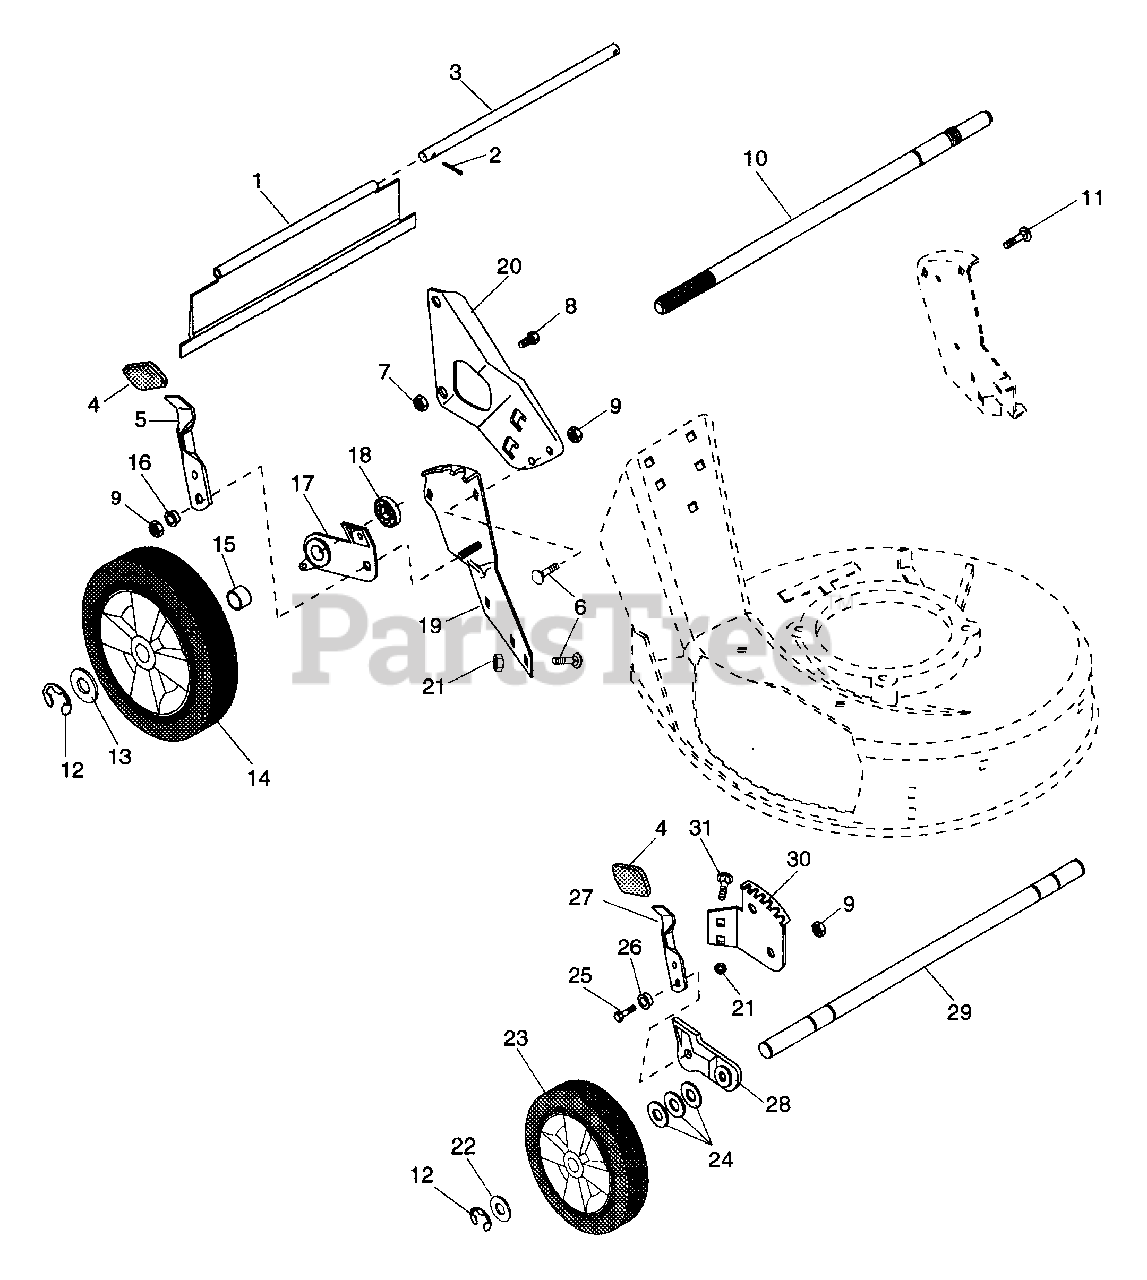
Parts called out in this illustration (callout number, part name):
1	REAR PROTECTIVE GUARD, PUSH
1	REAR PROTECTIVE GUARD, S.P.
2	PIN-COTR .06X.50
3	ROD
5	HEIGHT ADJUSTMENT LEVER
6	BLT-RDHDSQNK .312-18X.62SHTPL
7	NUT-LK-JAM-CTR .375-16 PL
8	HANDLEBAR STUD
9	NUT-LK .312-18 GR A PL
10	REAR AXLE,5/8 DIA
10	REAR AXLE-PUSH MOWER MM
10	REAR AXLE-PUSH MOWER
11	BLT-RDHDSQNK .31-18X1.0 SHT PL
12	RG-RTNG-EXT .500X.042 (E)
14	LH WHEEL
14	RH WHEEL
14	WHEEL
14	RH REAR WHEEL
14	LH REAR WHEEL
14	TIRE 10X1.75
14	10 1/2 TIRE SKIN
15	SPACER TUBE,PUSH LH
15	SPACER TUBE PUSH RH
15	SPACER TUBE, SELF PROPEL
16	BSHG-FLG .32X.500X.344X.880
17	REAR BRACKET & BEARING ASSEMBL
17	REAR BRACKET & BEARING ASSY RH
17	R.H. REAR ADJUSTOR BRACKET
17	REAR ADJUSTMENT BRACKET L.H.
17	L.H. REAR ADJUSTOR BRACKET
17	BRG-BALL .625X1.383X.50
19	QUADRANT, REAR - L.H.
19	REAR QUADRANT, R.H.
20	RH HANDLEBAR MTG. BRKT.
20	LH HANDLEBAR MTG. BRKT.
21	NUT-FLG. .312-18 PL
22	WSHR-FL-STL .505X.880X.072 PL
23	WHEEL
23	TIRE 7X1.50
23	WHEEL 7X1.75
24	WSHR-FL-STL .520X.827X.062 YZ
25	BLT-HEX .31-18X.88 PL GR2
26	BSHG-FLG .32X.500X.344X.880
27	FRONT HEIGHT ADJUSTMENT LEVER
28	LEFT ADJUSTOR BRACKET ASSEMBLY
28	RIGHT ADJUSTOR BRACKET ASSEMBL
28	RH ADJUSTER BRACKET
28	LH ADJUSTER BRACKET
29	FRONT AXLE
30	FRONT QUADRANT, L.H.
30	FRONT QUADRANT, R.H.
31	BLT-RDHDSQSHNK .31-18X.50 YZ
